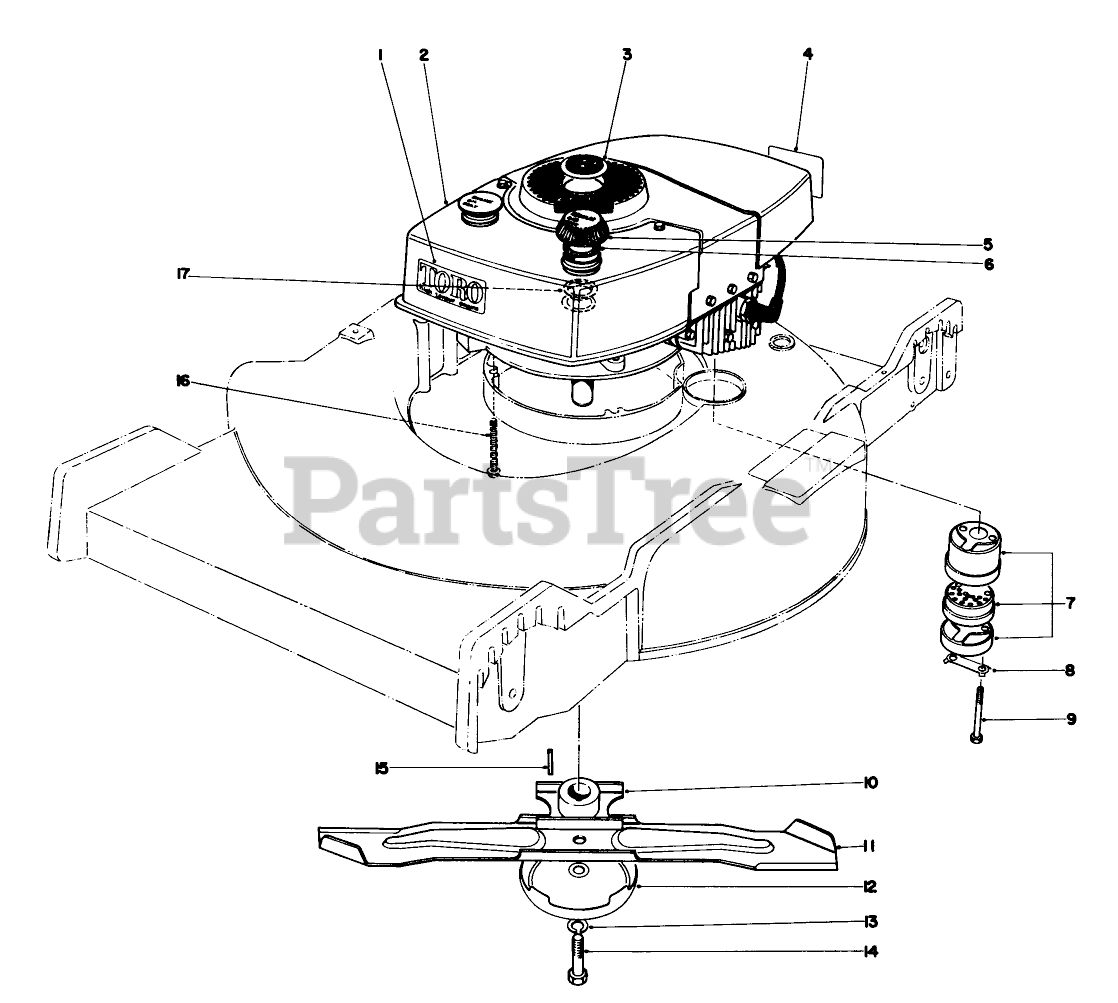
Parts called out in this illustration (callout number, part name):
2	Engine
6	GASKET
7	MUFFLER ASM
8	CLIP - LOCKING
9	SCREW-HH
10	BLADE RETAINER WA
13	WASHER-LOCK
14	BLADE SCREW
16	3/8-16 X 2-3/4 CAPSCR
